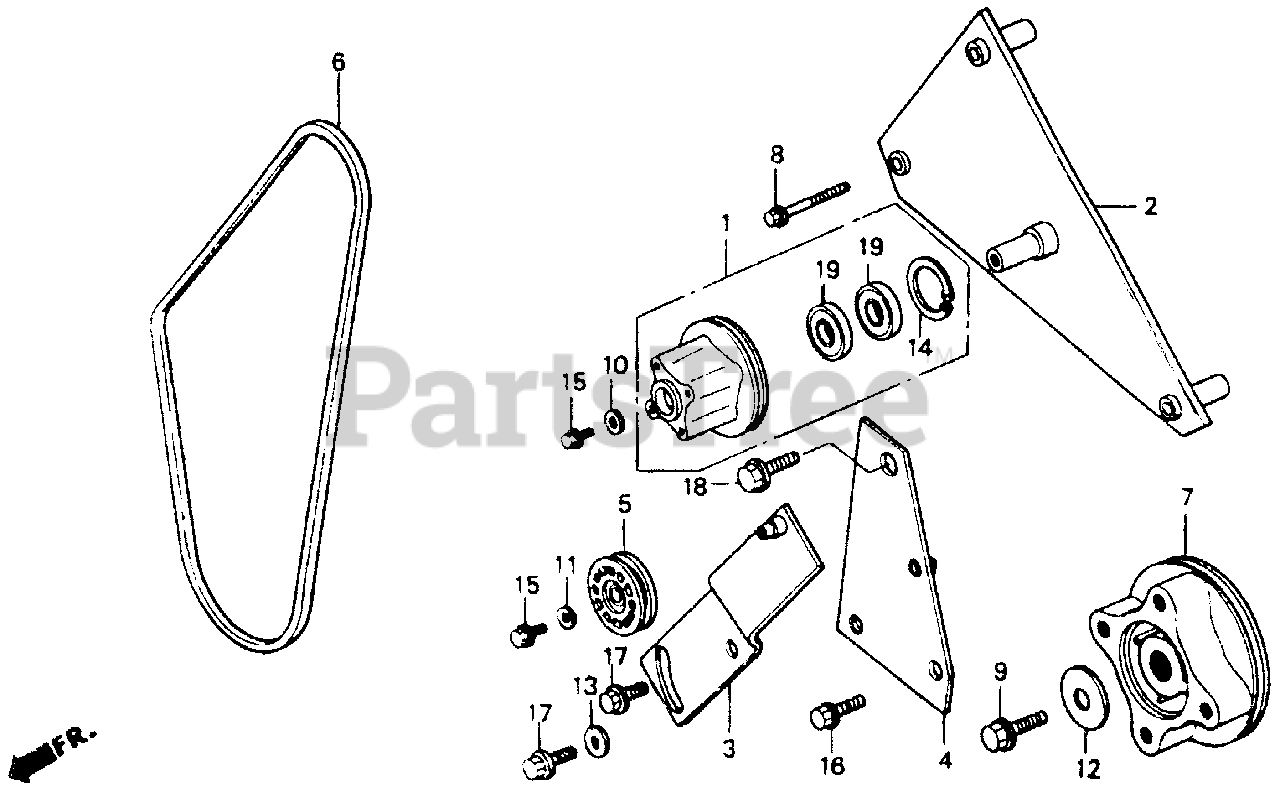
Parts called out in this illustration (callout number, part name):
1	PULLEY ASSY., COOLING FAN
2	BRACKET, COOLING FAN
3	ARM, TENSION
4	PLATE, TENSIONER ARM
5	PULLEY, TENSIONER (65MM)
6	BELT, ALTERNATOR (BANDO)
7	JOINT, PROPELLER SHAFT
8	BOLT, FLANGE (6X50)
9	BOLT, SPECIAL (10MM)
10	WASHER, GEARSHIFT DRUM SIDE
11	WASHER (6MM)
12	WASHER (10.5X40X4)
13	WASHER, PLAIN (10MM)
14	CIRCLIP (INNER) (32MM)
15	BOLT, FLANGE (6X12)
16	BOLT, FLANGE (8X20)
17	BOLT, FLANGE (10X20)
18	BOLT, FLANGE (10X20)
18	BOLT, FLANGE (10X25)
19	BEARING, RADIAL BALL (6201UU)
